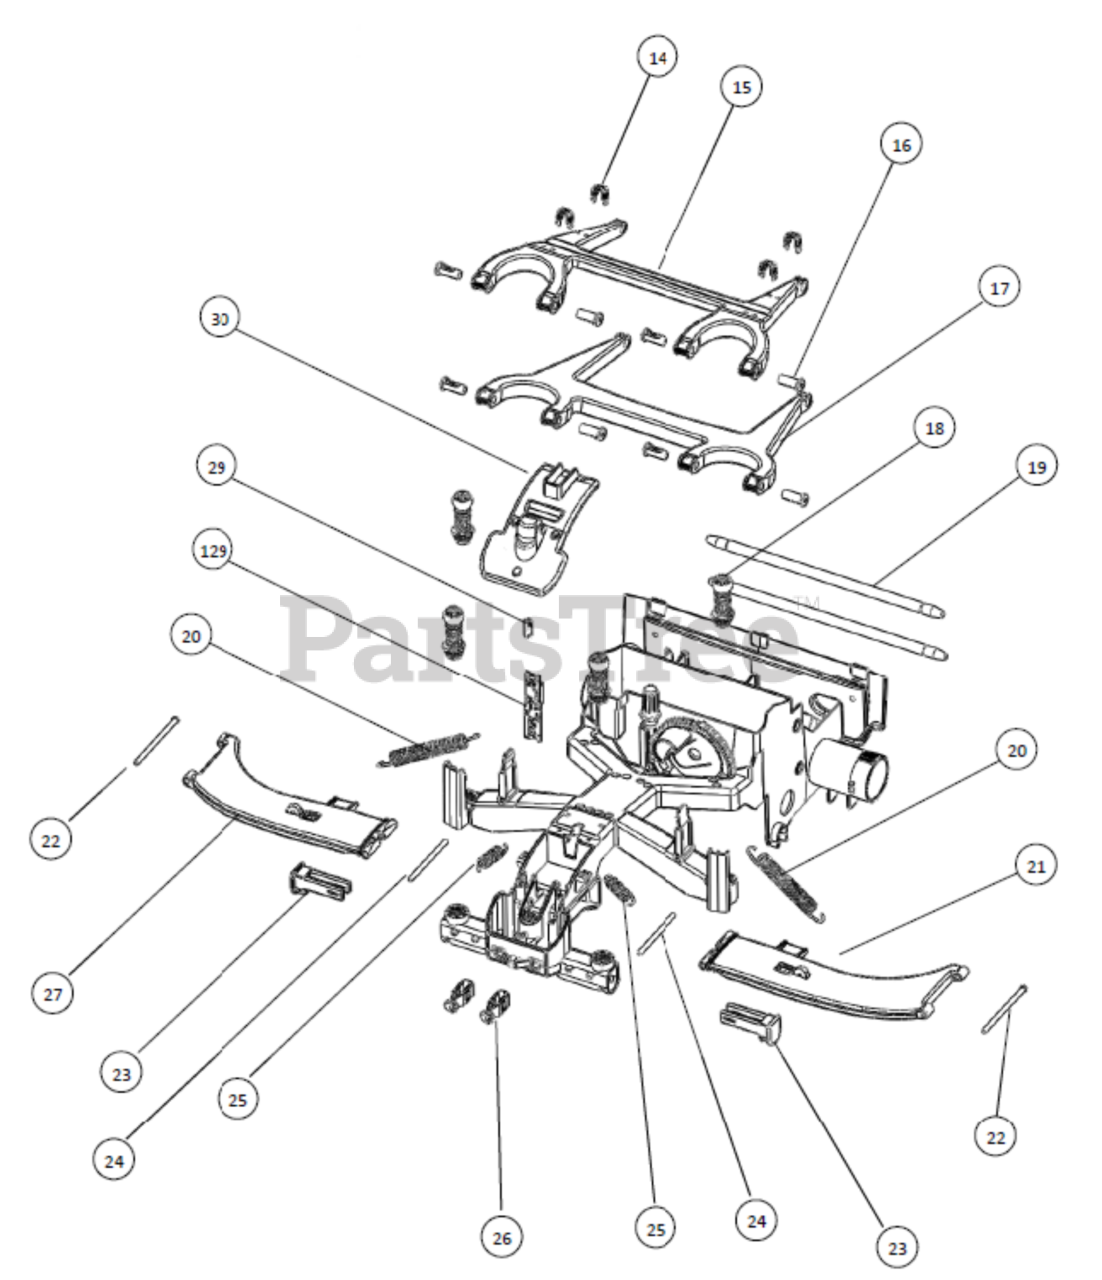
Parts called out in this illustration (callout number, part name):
14	WIRE LOCKER
15	MOWING UPPER ARM
16	MOWING MOTOS LOCKE
17	MOWING LOWER ARM
18	BALL JOINT ASSEMBL
19	SHAFT-PARRAL ASSEM
20	MOWING DECK SPRING
21	WING LEFT WITH FLOATER LIMITER
22	WING TO FLOATER SHAFT
23	WIRE SENSOR CAP
24	Y SHAFT TO WING
25	FLOATER SPRING
26	CHARGING CONTACT A
27	WING RIGHT WITH FLOATER LIMITER
29	FRONT WHEEL MAGNET
30	LIGHT COVER (COCKPIT)
129	RS FRONT BOARD (2019)
